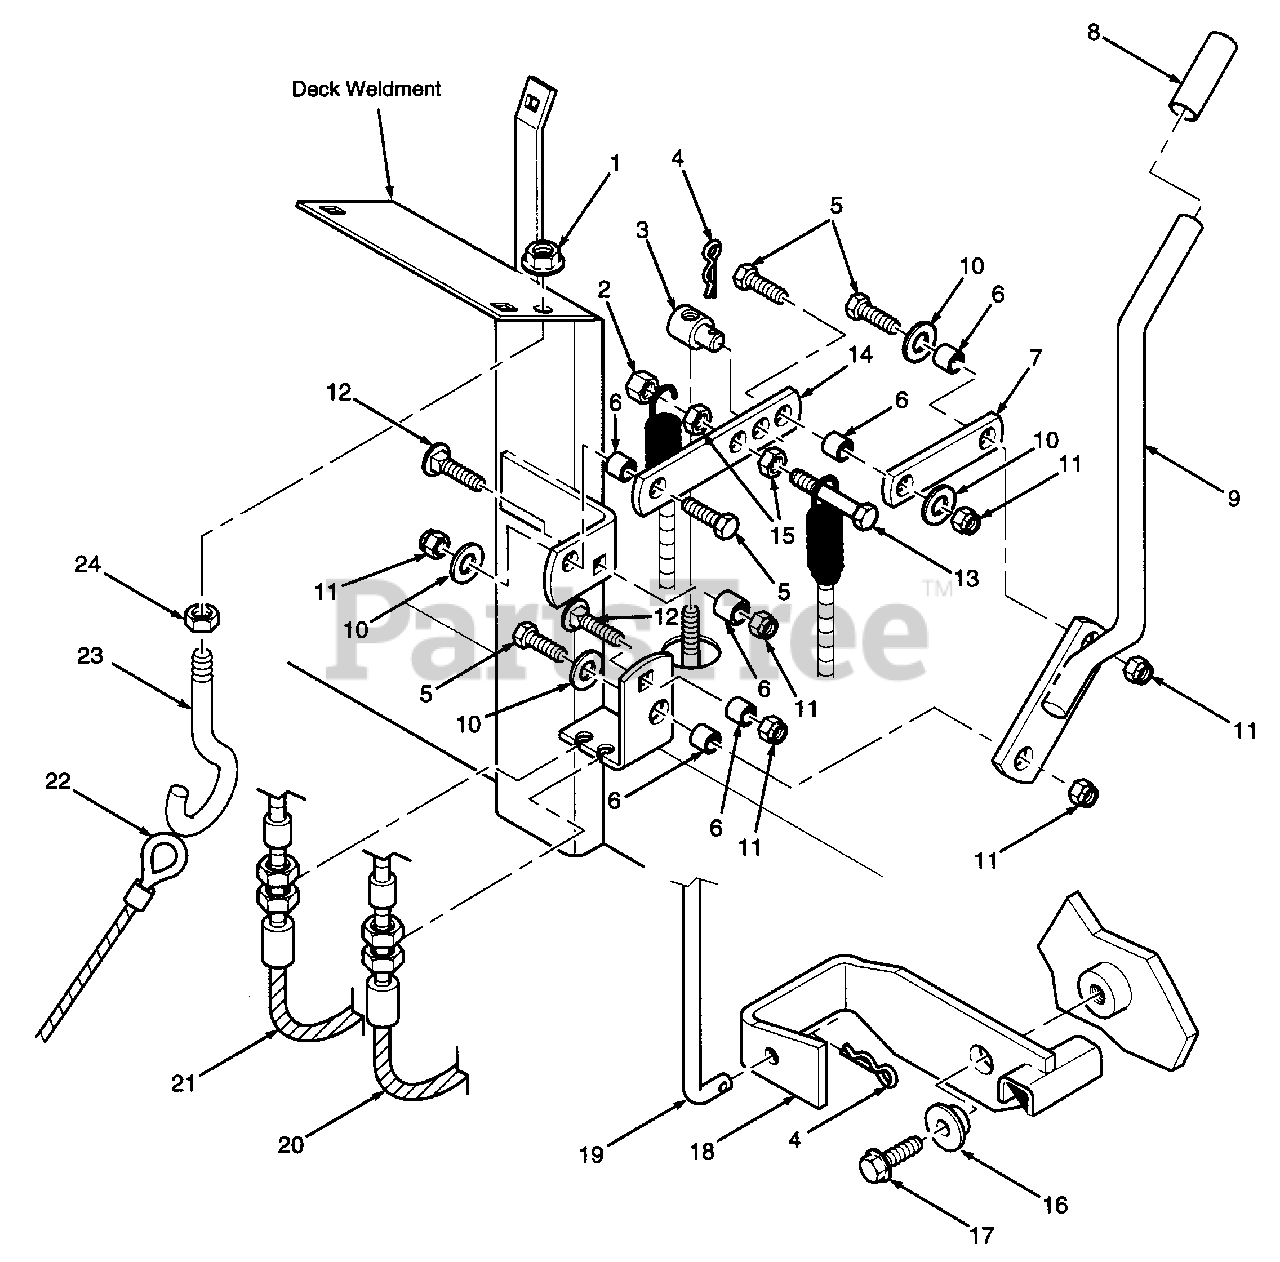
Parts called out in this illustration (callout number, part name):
1	SERR. FL. HH NUT, 3/8-16
2	HEX LOCKNUT, 3/8-16
3	SWIVEL
4	HAIRPIN COTTER(.094 X 1.62)
5	HEX HEAD BOLT, 3/8-16 X 1-1/4
6	SLEEVE, HYDRO LINKAGE
7	LINK, CAM
8	GRIP, PARKING BRAKE
9	HANDLE, PARKING BRAKE
10	FLAT WASHER, 3/8(.391 X .938 X .105)
11	HEX NUT, ELASTIC STOP 3/8-16
12	CARRIAGE BOLT, 3/8-16 X 1-1/4
13	HEX HEAD BOLT, 3/8-16 X 1-3/4
14	LEVER, BRAKE
15	HEX JAM NUT, 3/8-16
16	WASHER, NEUTRAL LOCK
17	SERR. FL. HH CPSCR, 3/8-16 X 1
18	BRACKET, NEUTRAL LOCK
19	ROD, NEUTRAL LOCK
20	CABLE ASSEMBLY, PARKING BRAKE R.H.
21	CABLE ASSEMBLY, PARKING BRAKE L.H.
22	CABLE WINCH
23	EYE BOLT, 3/8-16 R.H.
24	HEX NUT, 3/8-16
